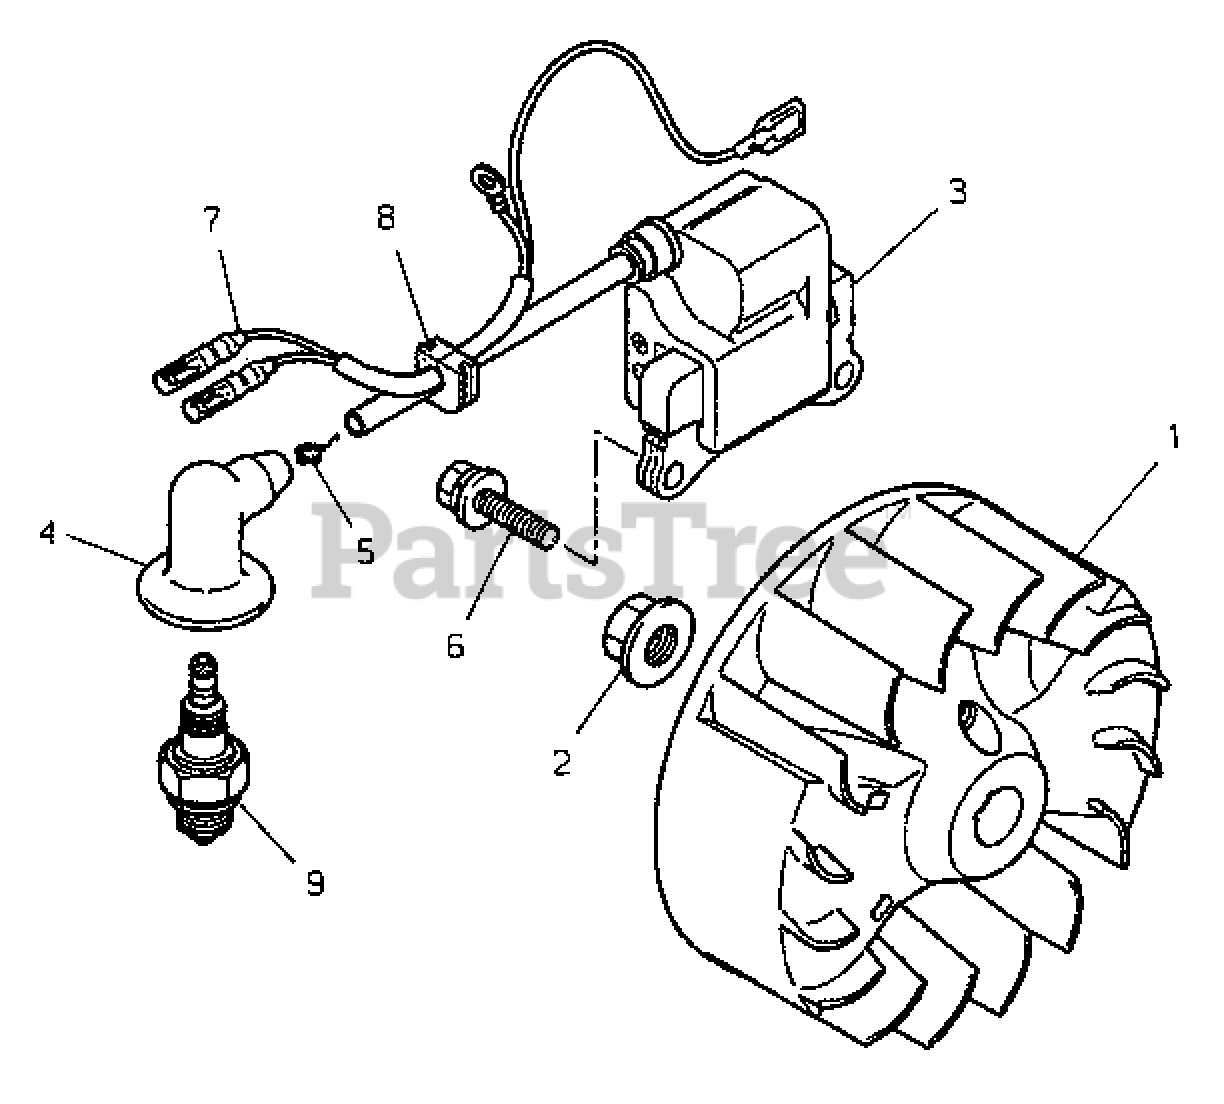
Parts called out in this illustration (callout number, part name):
1	ROTOR
3	IGNITION COIL ASSY
4	CAP, SPARK PLUG
5	TERMINAL, SPARK PLUG CAP
7	LEAD WIRE
9	SPARK PLUG -- BPMR-8Y
